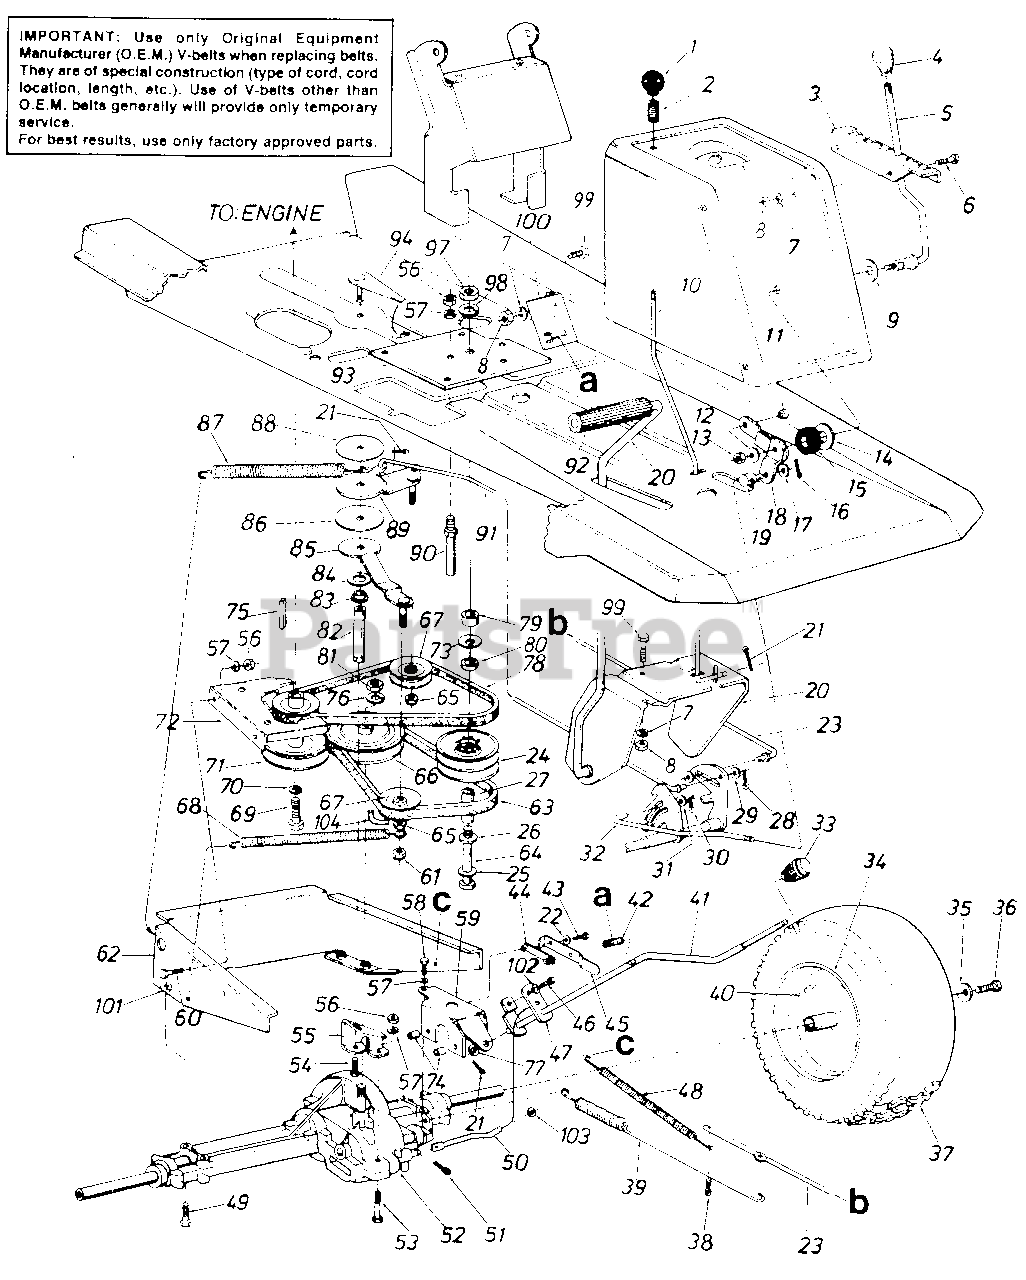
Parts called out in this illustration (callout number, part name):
1	Ball Knob 1/4-20 Thd. 1.25"
2	Compression Spring
5	Speed Control Lever
6	Truss Mach. Scr. 5/16-18 x .75" Lg.
7	L-Wash. 5/16" I.D.
8	Hex Nut 5/16-18 Thd.
9	Bell-Wash. .345" I.D. x .88"
10	Brake Locking Rod
12	Bell-Wash. .345" I.D. x .08"
13	Hex Cent. L-Nut 5/16-18 Thd.
14	Fl-Wash. .531" I.D. x 1.25" O.D.
15	Rubber Washer
16	Intern. Cotter Pin 1/2" Dia.
17	Fl-Wash. .34" I.D. x .68" O.D.
18	Speed Control Lever Brkt. Ass'y.
19	Ferrule-Engagement
20	Clutch/Brake Pedal Ass'y.
21	Cotter Pin 3/32" Dia. x .75"
22	Plastic Washer
23	Brake Rod
24	Variable Speed Pulley Ass'y.
25	Fl-Wash. .4" I.D. x 1.25" O.D.
26	Thrust Brg. 1.25" O.D. x .56" I.D.
27	Spacer Sleeve 2.71"
28	Cotter Pin 1/8" Dia. x 1.25"
29	Fl-Wash. .34" I.D. x .60" O.D.
30	Intern. Cot-Pin 5/16" Dia.
31	Fl-Wash. .34" I.D. x .60" O.D.
32	Speed Control Link
33	Shift Knob
34	Rear Wheel Rim Only
35	Bell-Wash. 345" I.D. x .88"
36	Hex L-Bolt 5/16-24 x .75" Lg.
37	Rear Wheel Ass'y.-Comp.
38	Cotter Pin 1/8" Dia. x 1.25
39	Extension Spring 17.0" Lg.
40	Air Valve
43	Hex Wash. Hd. Scr. #8 x .5" Lg.
44	Insulator Nut
45	Spring Switch
46	Hex Bolt 1/4-20 x .50" Lg.
47	Shift Lever Adjusting Link
48	Ext. Spring 81/4" Lg.
49	Hex Bolt 5/16-18 x 2.5n Lg.
50	Shift Rod
51	Intern. Cotter Pin
52	Transaxle
53	Hex Bolt 1/4-20 x 1.75" Lg.
54	Hex Bolt 3/8-24 x .75" Lg.
57	L-Wash. 1/4" I.D.
58	Self-Tap Mach. Scr. Type "C" 1/4-20 x 1.37" Lg.
59	Shift Lever Support Brkt.
60	Hex Bolt 1/4-20 x 1.00" Lg.
61	Hex L-Nut 3/8-24 Thd.
64	Hex Bolt 3/8-16 x 4.5" Lg.
65	Hex Ins. L-Nut 3/8-24 Thd.
66	5/8 V-Pulley .500" I.D. x 6"
67	V-Belt Idler .38" I.D. x 3.06"
68	Ext. Spring 50" O.D. x 6.37"
69	Hex Bolt 7/16-20 x 1.00" Lg.
70	L-Wash. 7/16" I.D.
71	Engine Pulley 500" O.D. & 3.56" O.D.
72	Upper Eng. Belt Guard
73	Bell-Wash. .4" I.D. x 1.12" O.D.
74	Spacer .256" I.D. x 50" O.D.
75	Sq.-Key 1/4" x 2.00" Lg.
76	L-Wash. 1/2" I.D.
77	Fl-Wash. 469" I.D. x .88" O.D.
78	V-Belt
79	Spacer 1.00" x .380" O.D.
80	Thrust Wash. .56 I.D. x 1.25" O.D.
81	Hex Nut 1/2-20 Thd.
82	Torque Rod
83	Flange Bearing .378
84	Fl-Wash. 640" I.D. x 1.24"
85	Idler Bracket Ass'y.
86	Thrust Wash. 635" I.D.
87	Extension Spring 758" Lg.
88	Thrust Wash. .385" I.D.
89	Idler Bracket Ass'y. For Clutch
90	Belt Guard Pin 1/4" Dia.
91	Clutch Rod
92	Foot Pad
93	Mtg. Brkt. Variable Pulley
98	L-Wash. 3/8 Heavy Duty
99	Hex Bolt 5/16-18 x .75" Lg.
100	Shift Lever Spring Brkt.
101	Hex Sems Nut 5/16-18 Thd.
102	Bell-Wash. .265" I.D. x .75" O.D.
103	Push on Retaining Ring
104	Belt Guard
